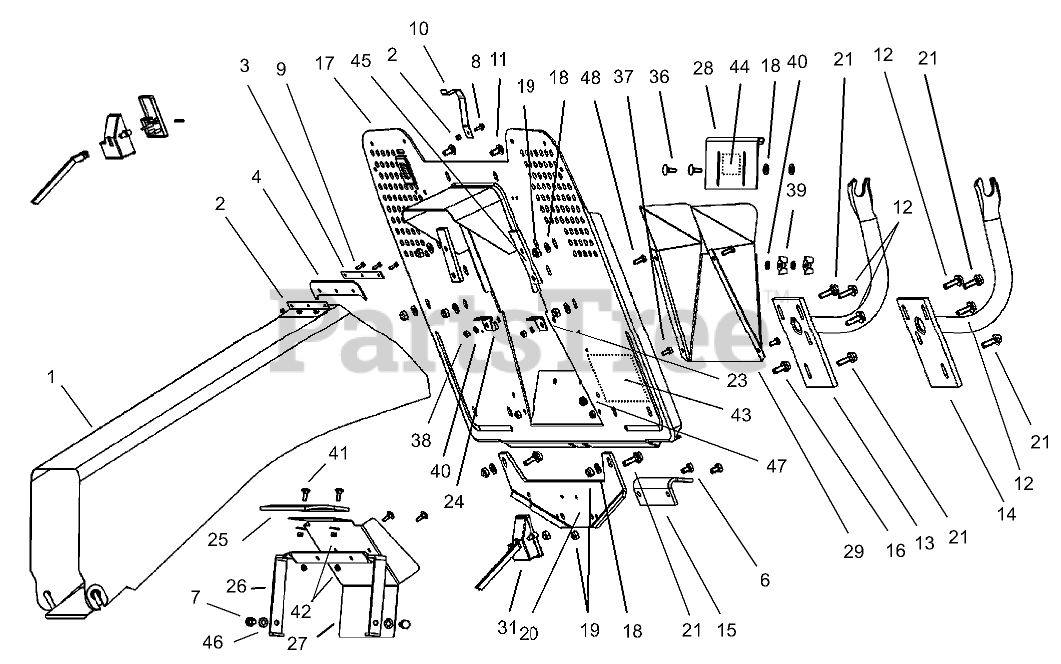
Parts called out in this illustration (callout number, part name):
1	Tunnel
2	NUT-HEX
3	PLATE-SUPPORT
4	SEAL-RUBBER
6	SCREW-HH
7	SCREW-HHF
9	SCREW-SFH
10	COVER-SWITCH
11	BOLT-CARRIAGE
13	SUPPORT-COLLECTOR, RIGHT
14	SUPPORT-COLLECTOR, LEFT
15	HITCH-TOW
16	SCREW-HEX
17	COLLECTOR PLATE ASM
18	WASHER-FLAT
19	NUT-LOCK, NI
20	SUPPORT-HITCH, TOW
21	SCREW-HEX
23	Support-Tunnel, Left
24	Support-Tunnel, Right
25	Shield-Rubber
26	BRACKET-SHIELD, PROTECTIVE
27	SHIELD-PROTECTIVE
28	Shield-Adjustable
29	Hopper-Receiving
31	OVERLOAD SWITCH ASM
37	SCREW-HH
38	NUT-LOCK
39	NUT-WING
40	WASHER-FLAT
41	BOLT-CARRIAGE
42	NUT-LOCK
43	DECAL-BYPASS, HYDRO
44	DECAL-POSITION, BAGGING
45	Plate-Reinforcing
46	Washer-Spring
47	Bushing
48	Screw-HH
